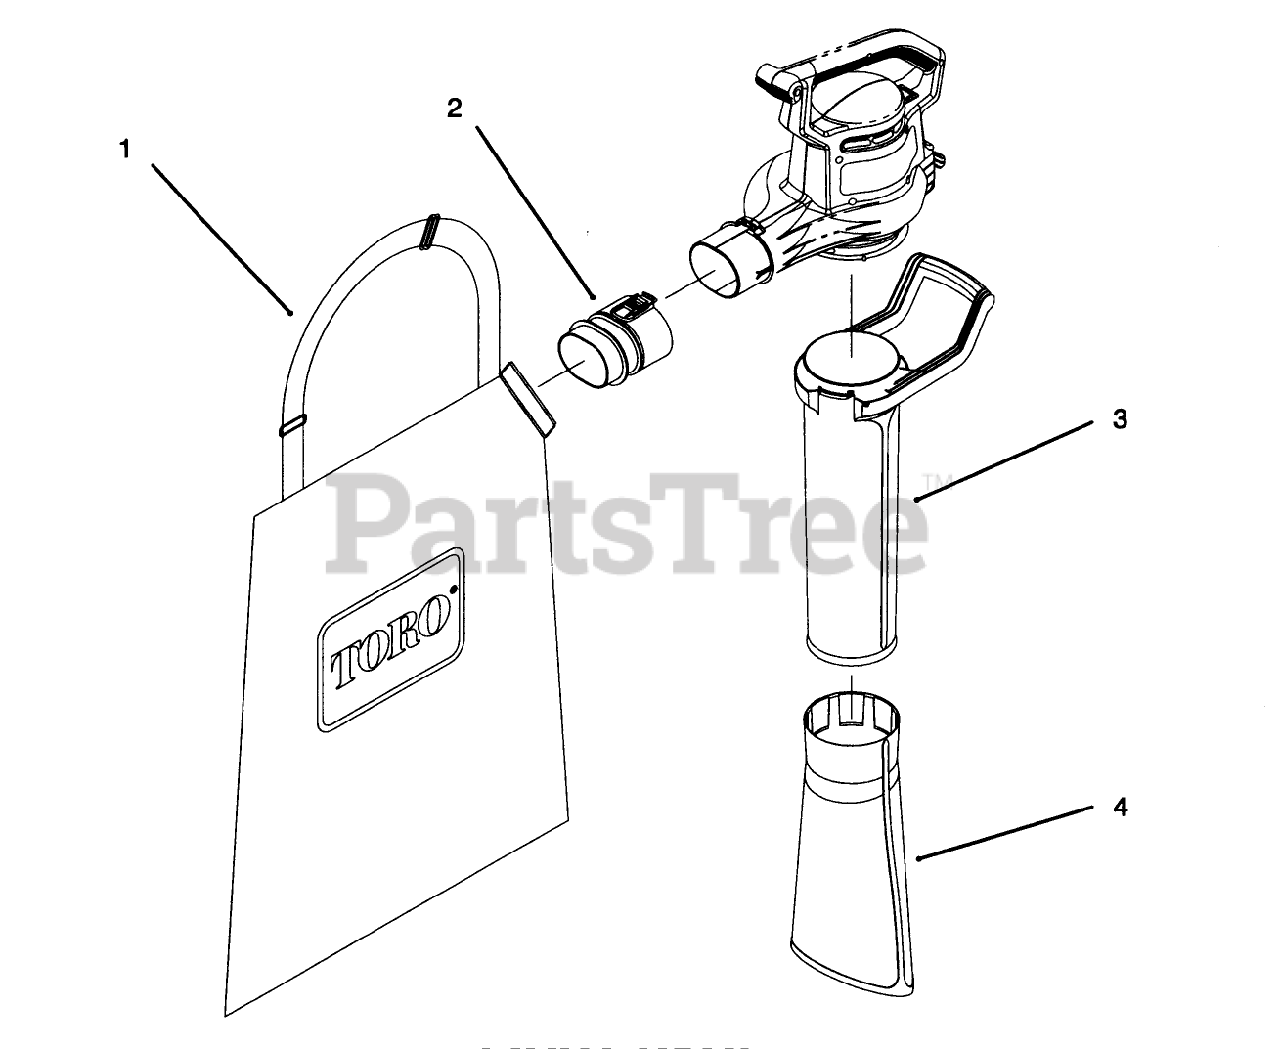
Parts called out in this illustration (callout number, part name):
1	BAG
2	TUBE - INLET
3	Tube-Vac
4	Tube-Vac
